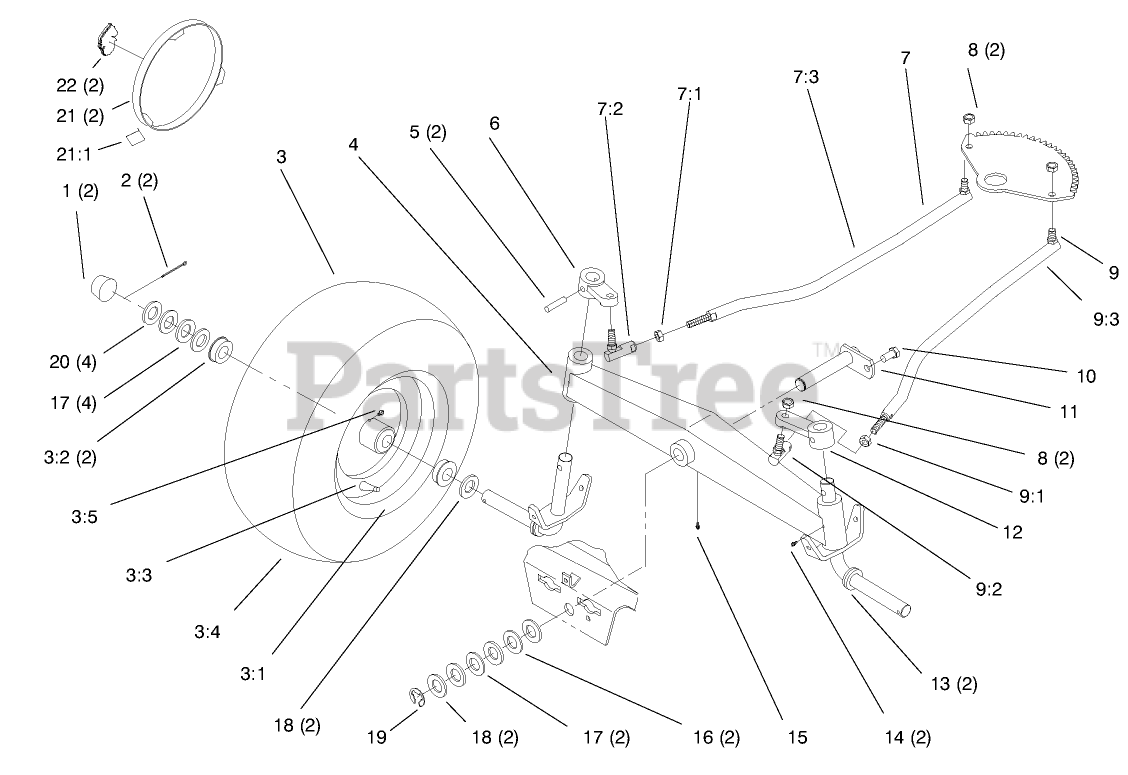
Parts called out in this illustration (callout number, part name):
1	CAP-HUB
2	PIN-COTTER
3:1	WHEEL ASM
3:2	BEARING-WHEEL
3:3	VALVE
3:4	TIRE (16 X 6.5-8) 2-PLY -2 WHEEL AXEL
3:5	ZERK-GREASE
4	AXLE ASM-FRONT
7	LINKAGE-STEERING, RH
7:1	Nut-Hex Jam
9	LINKAGE-STEERING, LH
9:1	Nut-Hex Jam
10	SCREW-HWH, TAPTITE
11	PIN-AXLE
14	FITTING-GREASE
15	FITTING-LUBE, 45 DEG
16	WASHER
17	WASHER
18	WASHER-SHIM
19	E-RING
20	WASHER-PLAIN
